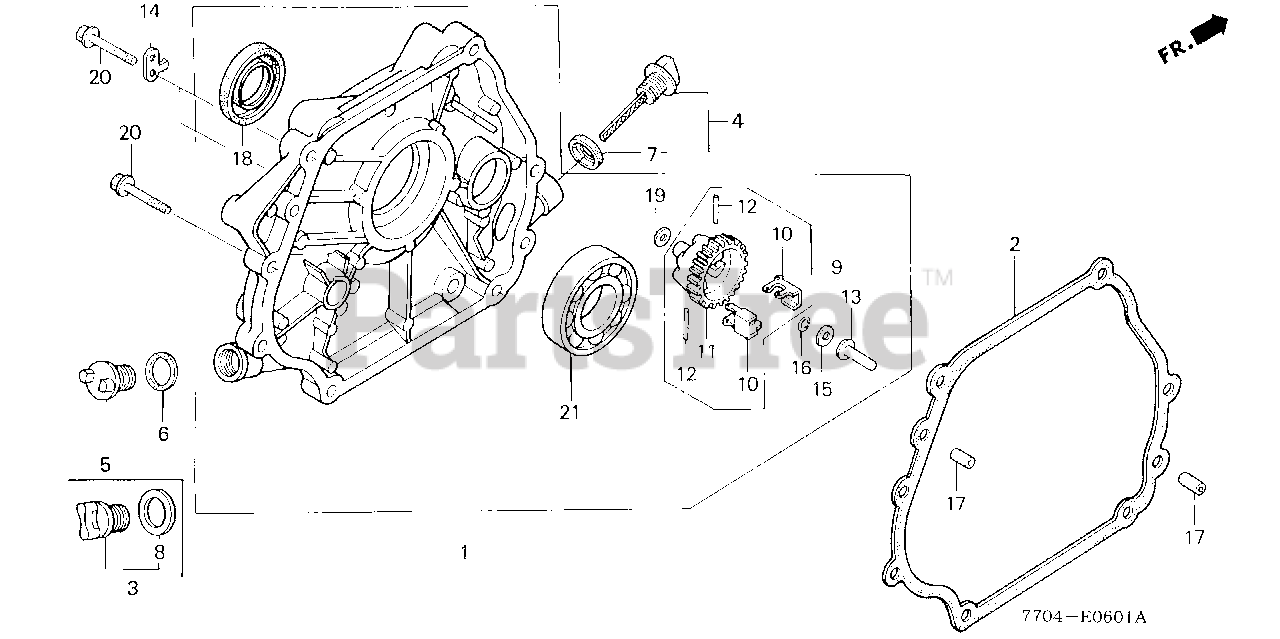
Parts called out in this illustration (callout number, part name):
1	COVER ASSY., CRANKCASE
2	GASKET, CASE COVER
3	CAP ASSY., OIL FILLER
4	CAP ASSY., OIL FILLER
5	CAP, OIL FILLER
6	GASKET, OIL FILLER CAP
7	GASKET, OIL FILLER CAP
8	GASKET, OIL FILLER CAP
9	GOVERNOR ASSY.
10	WEIGHT, GOVERNOR
11	HOLDER, GOVERNOR WEIGHT
12	PIN, GOVERNOR WEIGHT
13	SLIDER, GOVERNOR
14	STAY, WIRE CLIP (A)
15	WASHER (6X16)
16	CLIP, GOVERNOR HOLDER
17	PIN, DOWEL (8X12)
18	OIL SEAL (30X46X8)
19	WASHER, PLAIN (6MM)
20	BOLT, FLANGE (8X35)
21	BEARING, RADIAL BALL (6206)
